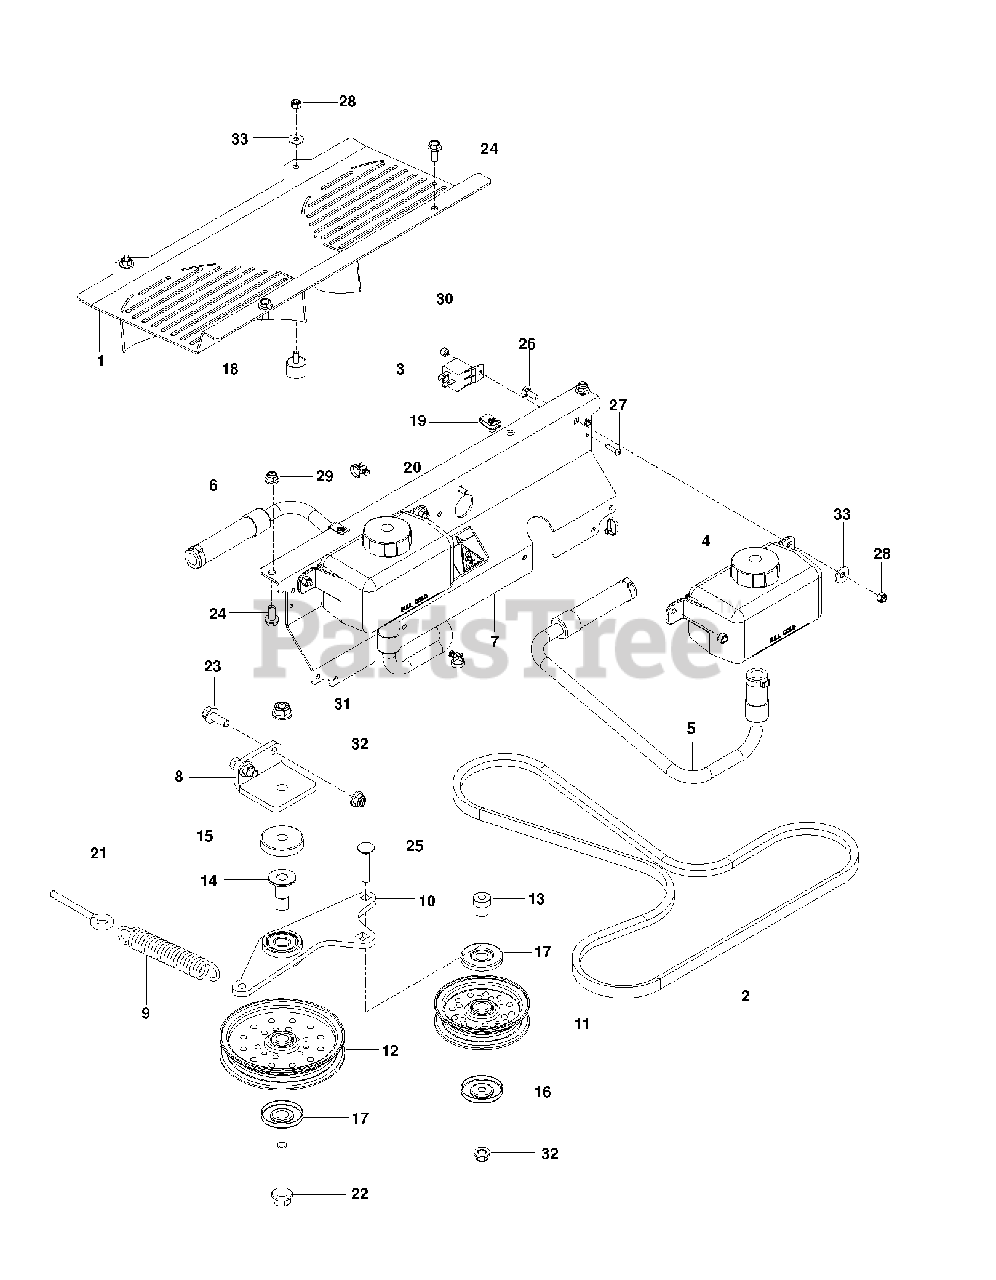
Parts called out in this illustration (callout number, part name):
11	IDLER PULLEY
12	IDLER, FLAT, 5.5"
13	PIVOT, IDLER
15	SHIELD, DUST
16	DUST SHIELD
17	SHIELD, DUST
18	BUMPER, MALE STUD, 1/4-20
19	U-CLIP 5/16-18 NUT RETAINER
21	EYE BOLT 5/16 X 3.50
22	HFFS 1/2-13 X 3 GD 5 ZD
23	HHFS 3/8-16 X 1 GRD 5 ZD
24	HHFS 5/16-18 X 3/4
25	RHSNB 3/8C X 2
26	RHSNB 1/4C X 3/4
27	SCR #10-24 X .75 SKT HD BLK
28	NUT 1/4-20 NYLOC
29	5/16-18 NYLOC FLANGE NUT
30	NUT 10-24 NYLOC
31	NUT, 1/2-13 HEX FLG NYLOC ZD
32	NUT 3/8-16 HEX FLG NYLOC ZD
33	WASHER 1/4 FLAT
